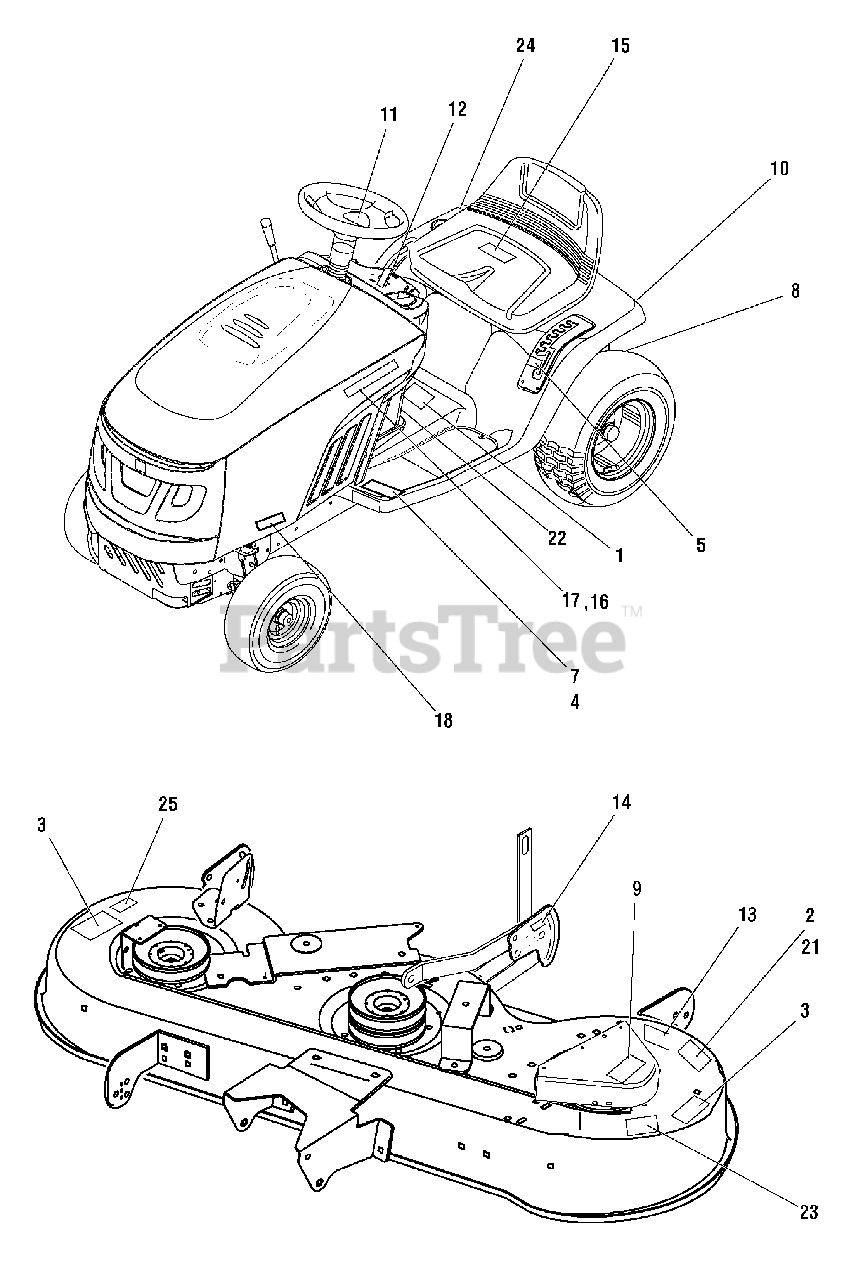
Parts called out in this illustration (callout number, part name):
1	DECAL, Umber
2	DECAL, No Step
3	DECAL, Danger Cutting Deck, Do not Operate without Deflector
3	DECAL, Cut Hand/Foot, FC
4	DECAL, Drive Pedal
5	DECAL, Height of Cut
5	DECAL, Height of Cut or deck level
7	DECAL, Belt / Clutch
8	DECAL, Weight Limitation
9	DECAL, 46 in Deck
10	DECAL, Snapper Logo, Rear
11	DECAL, Snapper Logo, Steering Wheel
12	DECAL, Dash, Electric PTO
13	DECAL, Gauge Wheel Instruction, ENG/FC
14	DECAL, Deck Level, ENG/FC
15	DECAL, Auto Drive Dump Valve
16	DECAL, Snapper Logo, Hood, Right
17	DECAL, Snapper Logo, Hood, Left
18	DECAL, LT130/23 HP
21	DECAL, No Step, FC
22	DECAL, Danger, FC
23	DECAL, Cut Hand/ Foot, FC
24	DECAL, Deck Level Position, ENG/FC
25	DECAL, Warning - Pinch Point
